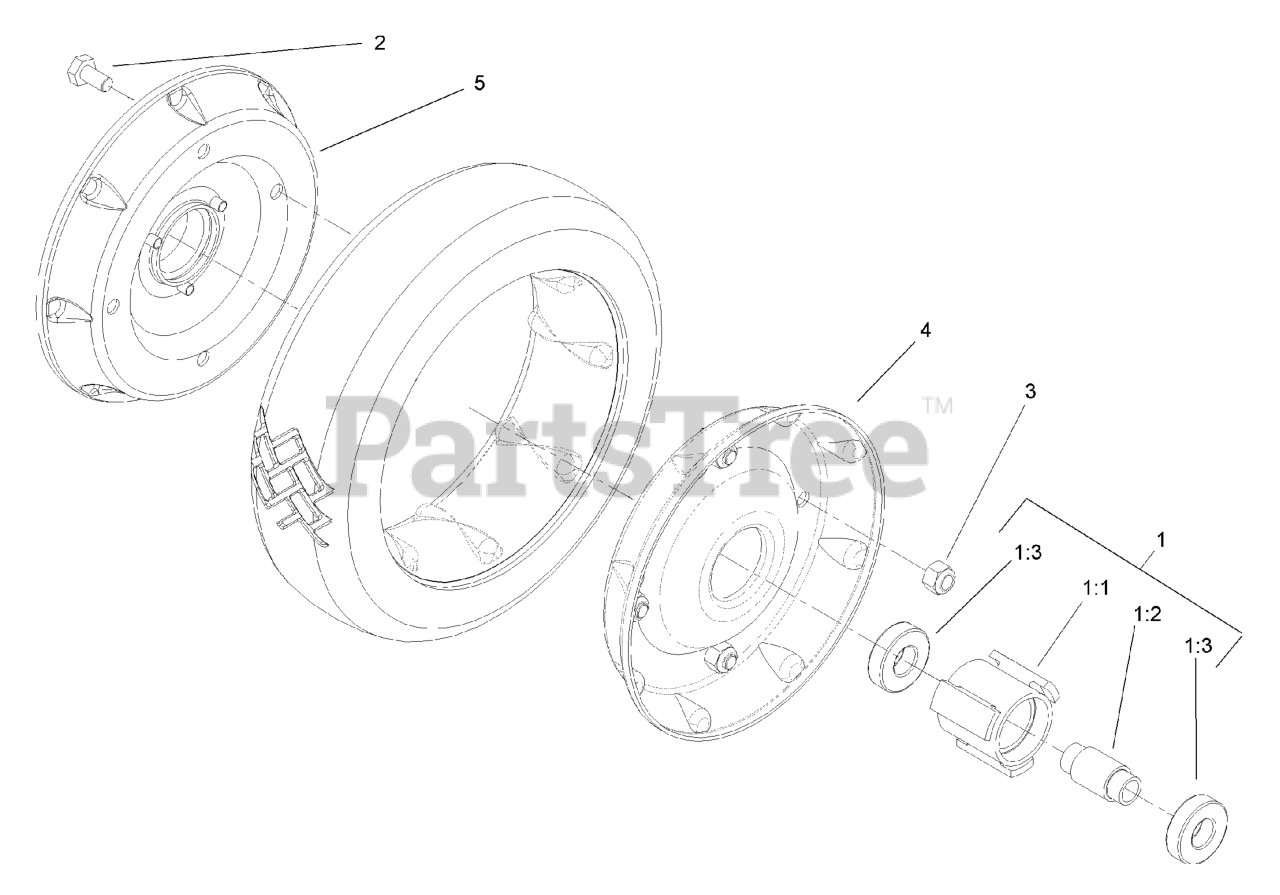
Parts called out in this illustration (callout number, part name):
1	Hub And Bearing Asm
1:1	HUB-BEARING
1:2	SPACER-BEARING
1:3	BEARING-WHEEL
2	SCREW-HH
3	NUT-LOCK, NI
